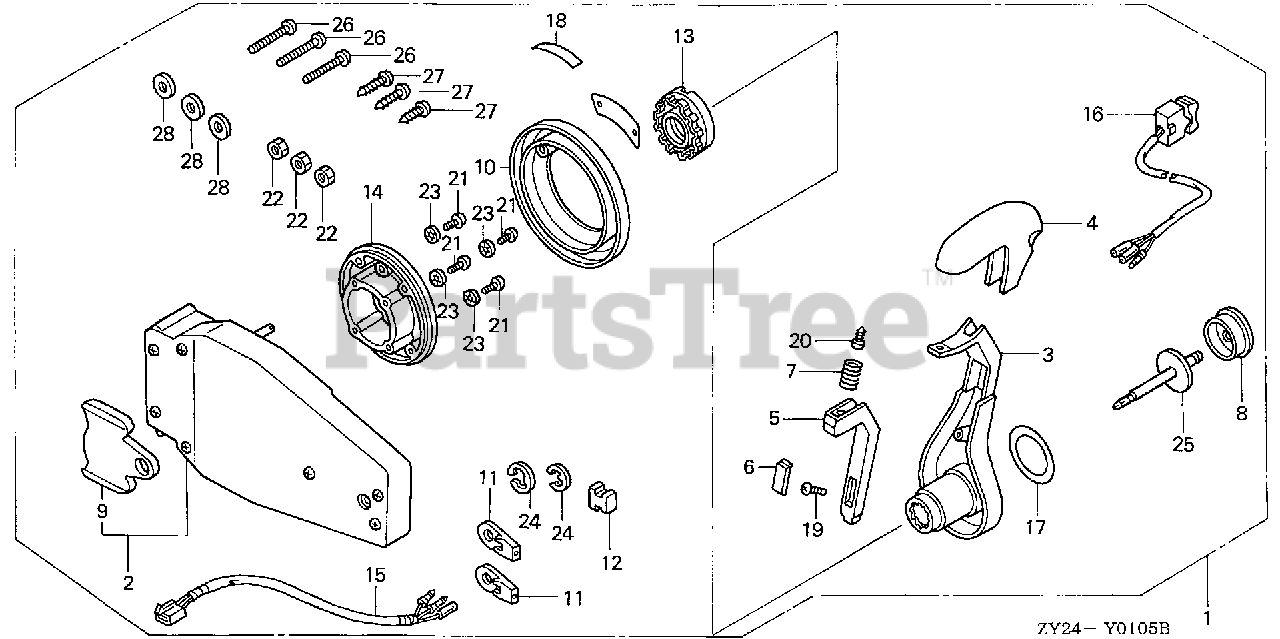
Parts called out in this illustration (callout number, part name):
1	BOX KIT, REMOTE CONTROL (FLUSH MOUNT)(L)
2	HOUSING ASSY., L. (INNER) (FLUSH MOUNT)
3	HANDLE, REMOTE CONTROL
4	COVER, GRIP
5	ARM, NEUTRAL LOCK
6	COVER, LOCK ARM
7	SPRING, NEUTRAL LOCK ARM
8	BUTTON, THROTTLE
9	PLATE, DWELL
10	COVER ASSY.
11	TERMINAL, CABLE
12	SPACER, CABLE CLAMP
13	HOLDER, NEUTRAL LOCK
14	BASE
15	SUB-HARNESS ASSY., POWER TRIM-TILT (C)
16	SWITCH ASSY., POWER TRIM-TILT (C)
17	MARK, HANDLE FLUSH MOUNT
18	MARK, FLUSH MOUNT
19	SCREW, TRUSS (4X12)
20	SCREW, PAN (5X10)
21	SCREW, PAN (5X30)
22	NUT, HEX. (6MM)
23	WASHER, LOCK (5MM)
24	E-RING (6MM)
25	SHAFT, THROTTLE BUTTON
26	SCREW, PAN (6X35)
27	SCREW, TAPPING (6X30)
28	WASHER, PLAIN (6MM)
